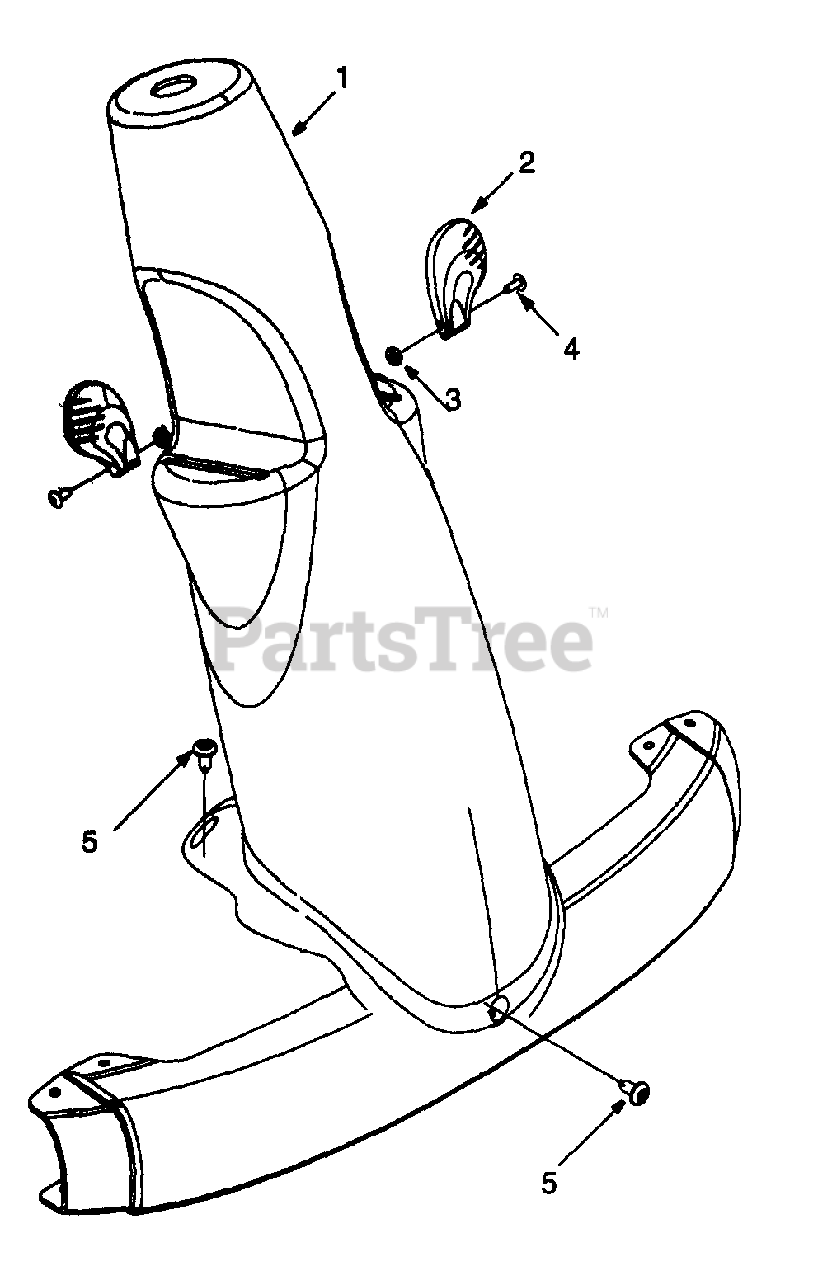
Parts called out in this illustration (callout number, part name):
1	Steering Column: Black
2	Control Knob
3	Hex Nut 8-32
4	Pan Head Machine Screw #8-32
5	Hex Screw TT 1/4-20 x .50"
